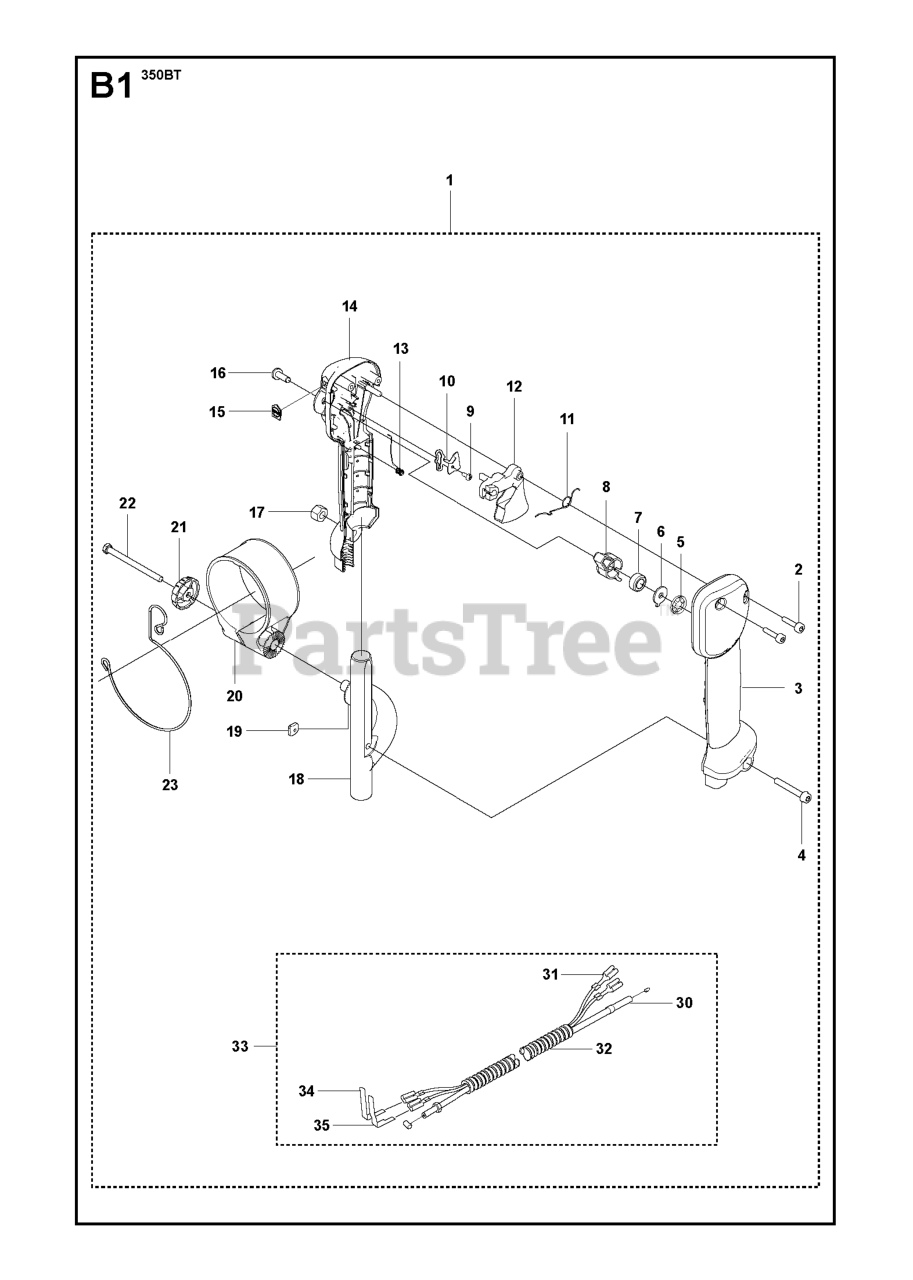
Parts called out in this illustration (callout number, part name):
1	HANDLE ASSY 150BT
2	SCREW
3	HANDLE HALF (R)
7	SPRING RUBBER
8	LEVER STOP
12	TRIGGER 848L5W34C0
14	HANDLE HALF (L)
16	SHAFT PIVOT
18	HOLDER, HANDLE
19	SQUARE NUT M5
21	KNOB
30	CABLE COMP
31	RP CORD
33	WIRING ASSY 370BTS / 350BT
34	CONTACT SPRING
35	CONTACT SPRING
